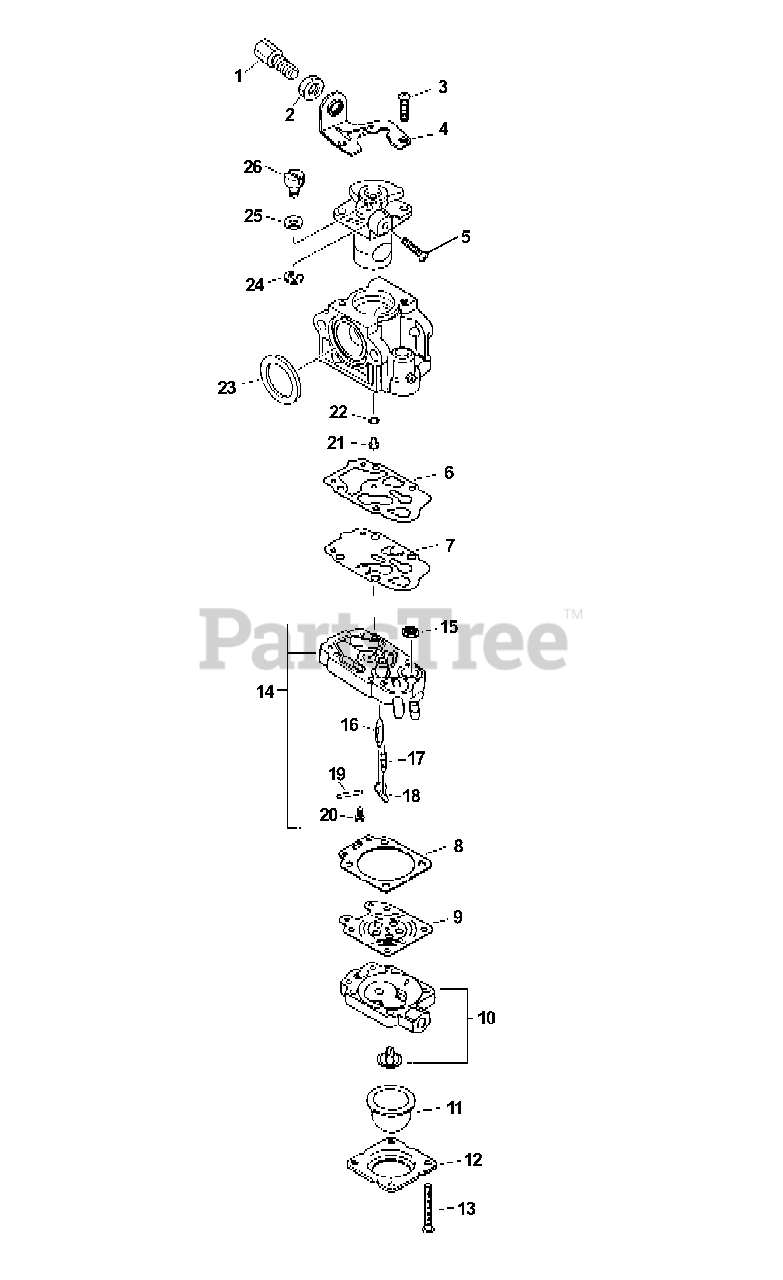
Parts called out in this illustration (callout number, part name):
1	ADJUSTER, THROTTLE CABLE
2	NUT, ADJUSTER LOCK M7
4	BRACKET, THROTTLE CABLE
6	GASKET, PUMP
7	DIAPHRAGM, PUMP
8	GASKET, METERING
9	DIAPHRAGM, METERING
10	BODY ASSY, PURGE
11	BULB, PURGE
12	RETAINER, PURGE BULB
14	BODY ASSY, PUMP
15	STRAINER
16	VALVE, INLET NEEDLE
17	SPRING, METERING LEVER
18	LEVER, METERING
19	PIN, METERING LEVER
21	JET, MAIN
23	SEAL
